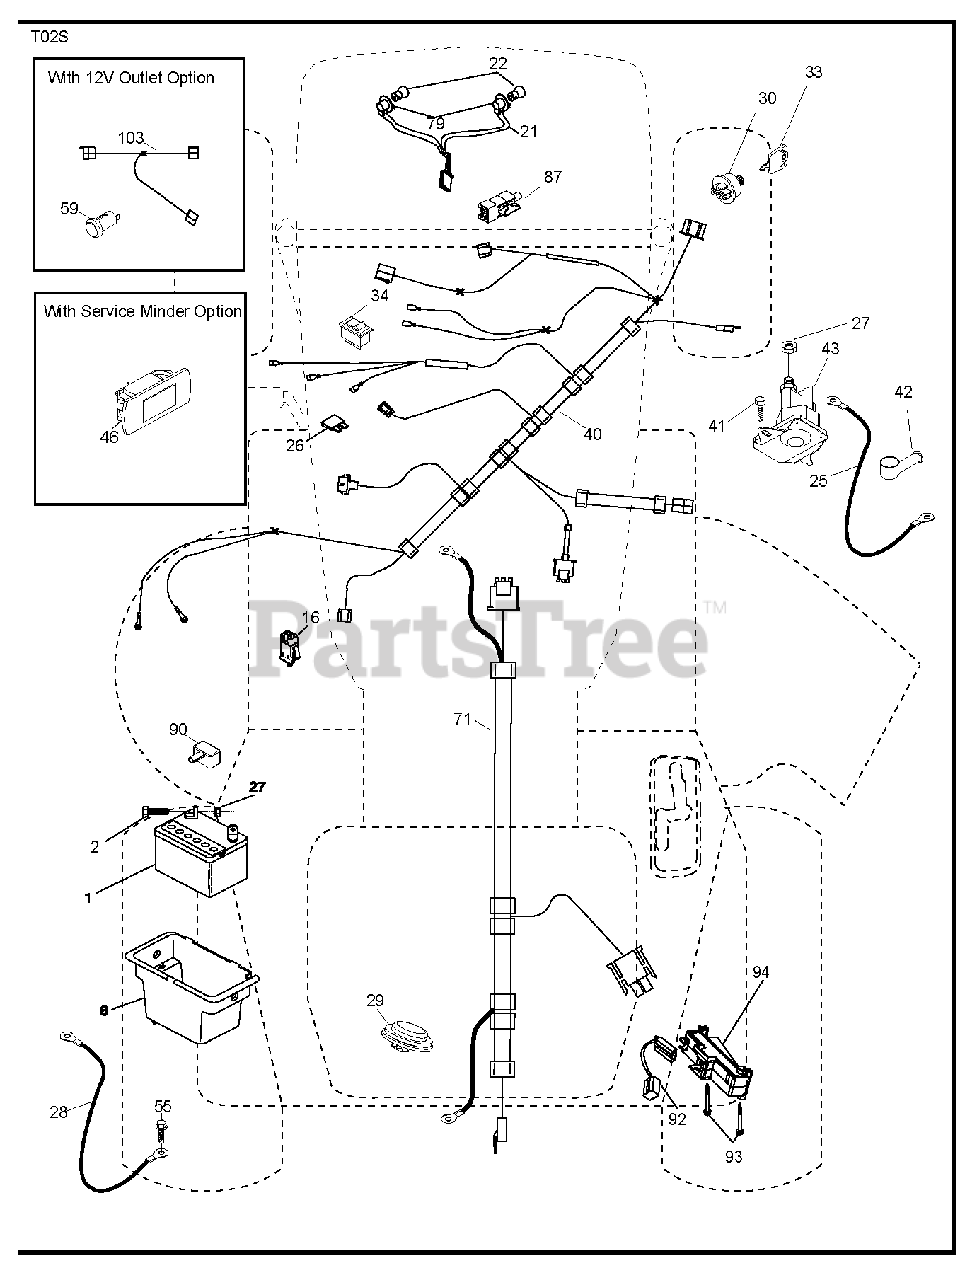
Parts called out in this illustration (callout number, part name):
1	Battery, Dry 30 Amp
2	BOLT.HEX.1/4.X.3/4.DICHROMATE
8	BOX.BATTERY.MNT.REAR.L
16	SWITCH INTERLOOK PUSH-IN
21	HARNESS.LIGHT W/4152J BULBS
25	CABLE.STARTER.6GA.BL/RED.14.
26	FUSE 20AMP
27	NUT
28	CABLE.BLACK.18"REAR.BA
29	SWITCH.SEAT.DELTA.OPC.
30	SWITCH.IGN.DELTA.W.LGH.ROS
33	KEY.CHAIN.BLISTER.PACK.GEN.INT
40	HARNESS IGN. DASH
41	SCREW
42	TERMINAL COVER
43	SOLENOID.W/BRASS.PLUNGER
55	SCREW 5/16"
71	HARNESS.IGN.CHASS.TEX.REAR.BAT
79	BULB HOLDER ASM.
87	SWITCH.INTRLCK.CLUTCH.
90	COVER, TERMINAL BATTERY
92	HARNESS.PIGTAIL.CONSLE
93	SCREW.PLASTITE
94	MODULE.REVERSE.ROS
